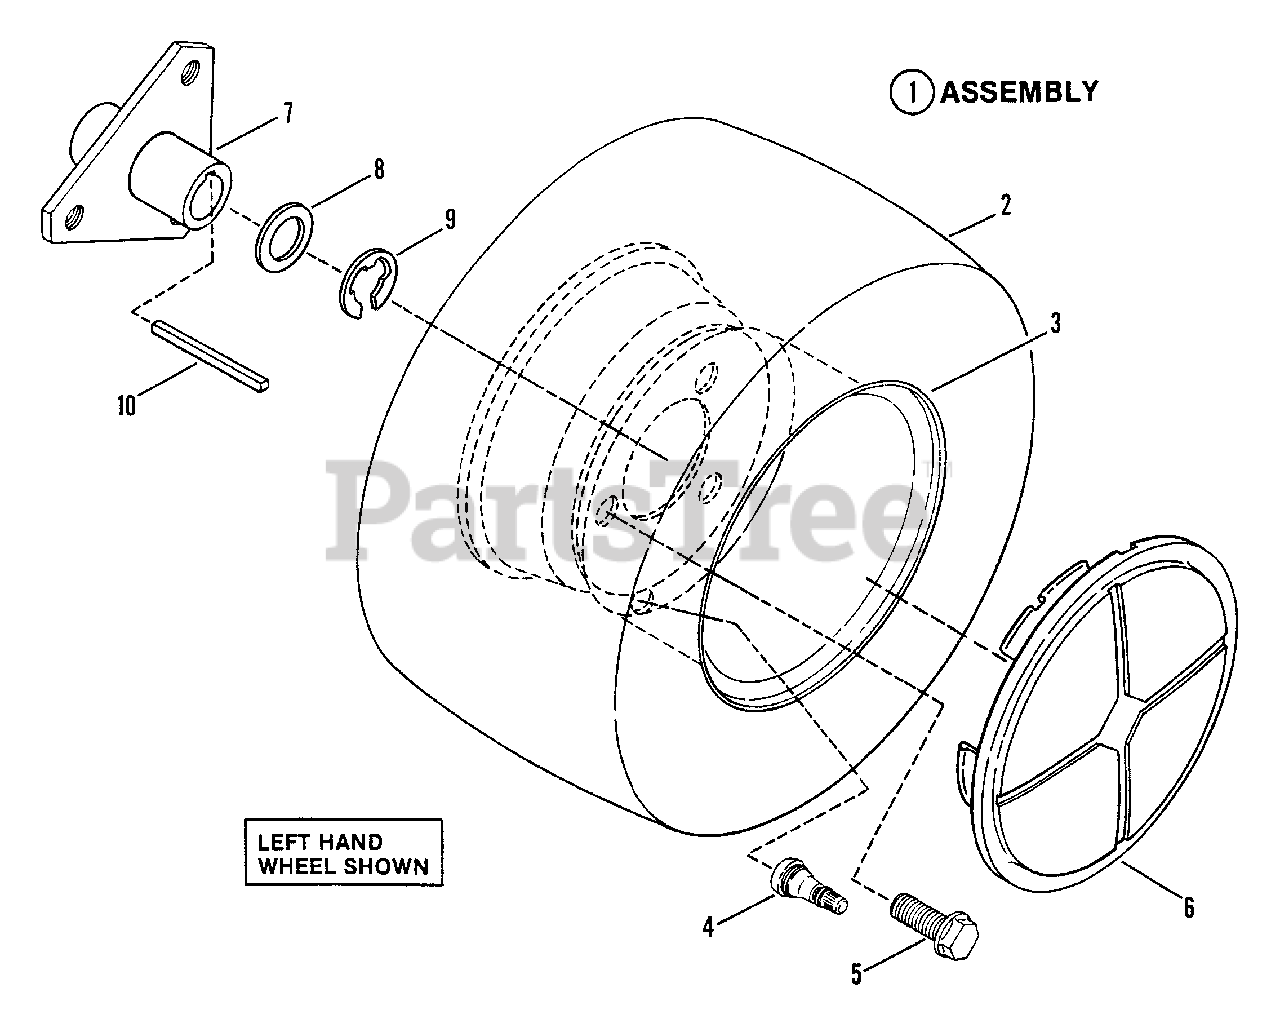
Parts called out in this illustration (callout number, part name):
1	ASSEMBLY, Rear Tire & Rim (LT125G41)
1	ASSEMBLY, Rear Tire & Rim (LT125G33 & RLT125G33)
2	TIRE, 18-8.50 x 8
2	TIRE, 18-7.50 x 8
3	RIM, 8 x 7
3	RIM, 8 x 5.375
4	VALVE, Air (Snap-in)
5	BOLT, 1/2-20 x 3/4" Lug
6	WHEEL-COVER
7	HUB, Rear Wheel
8	WASHER
9	RING, Retaining
10	KEY, Square, 3/16 x 2 1/2"
